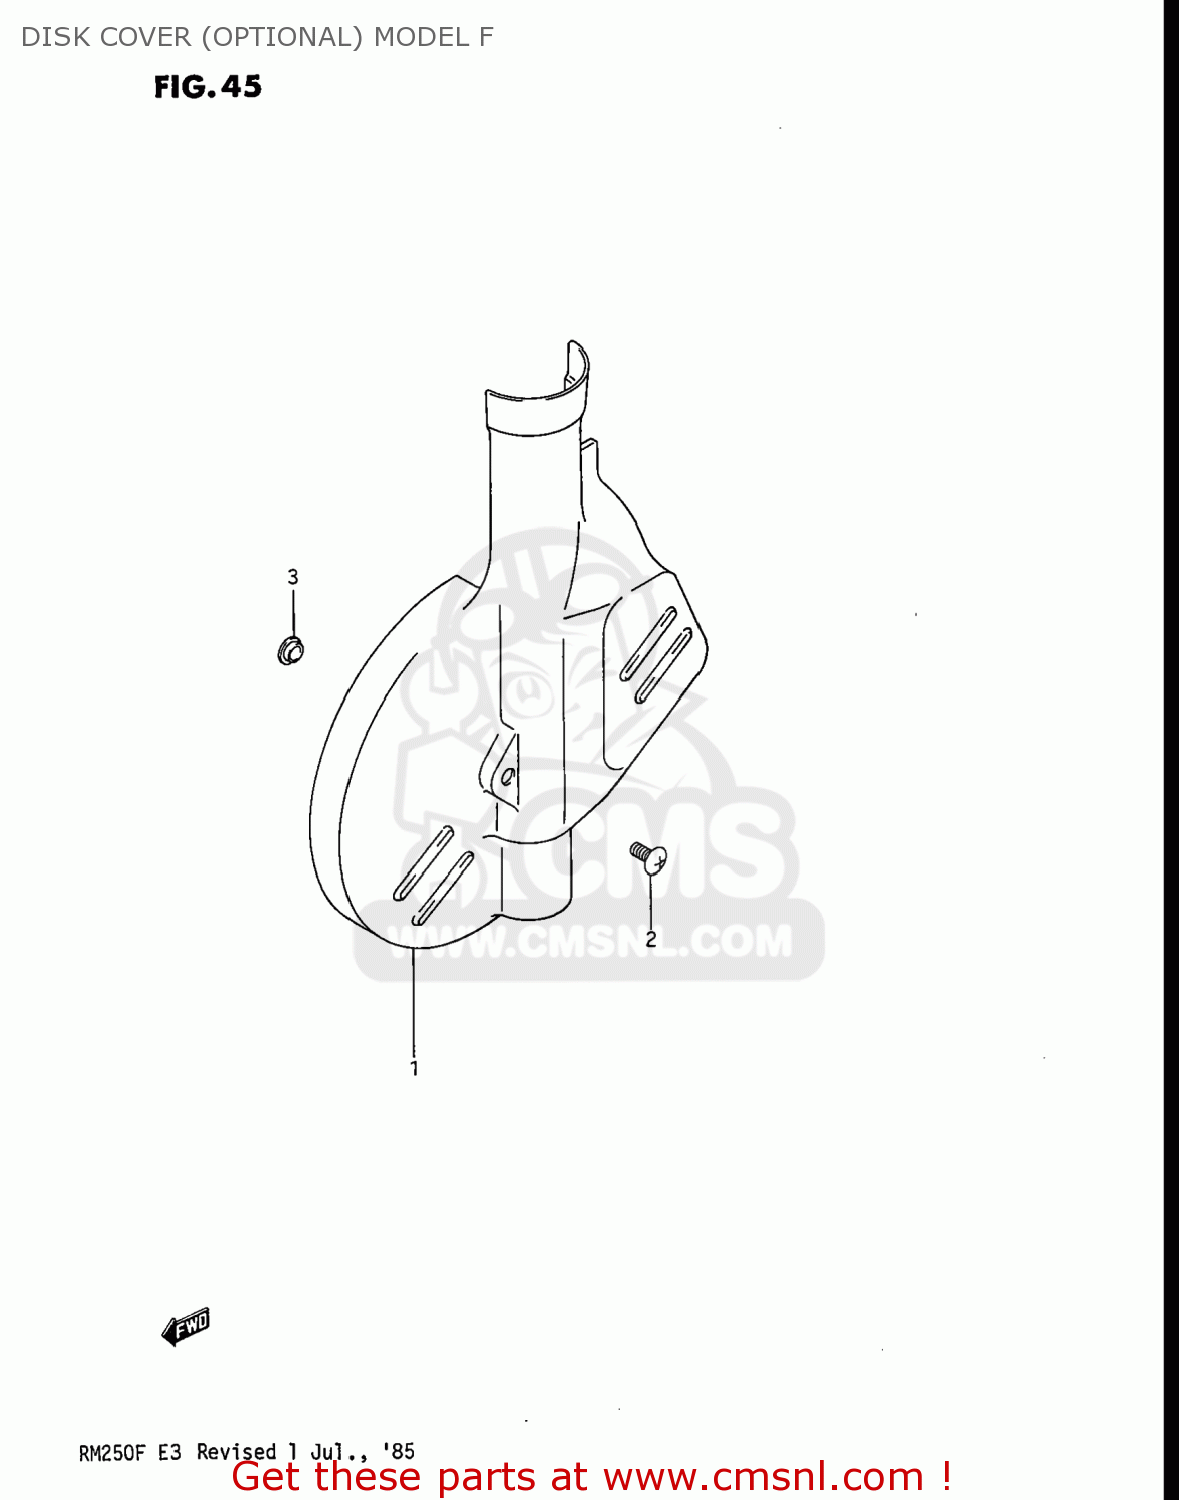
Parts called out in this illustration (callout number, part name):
1	COVER,FRONT BRAKE DISC
2	SCREW(8X12)
3	WASHER
